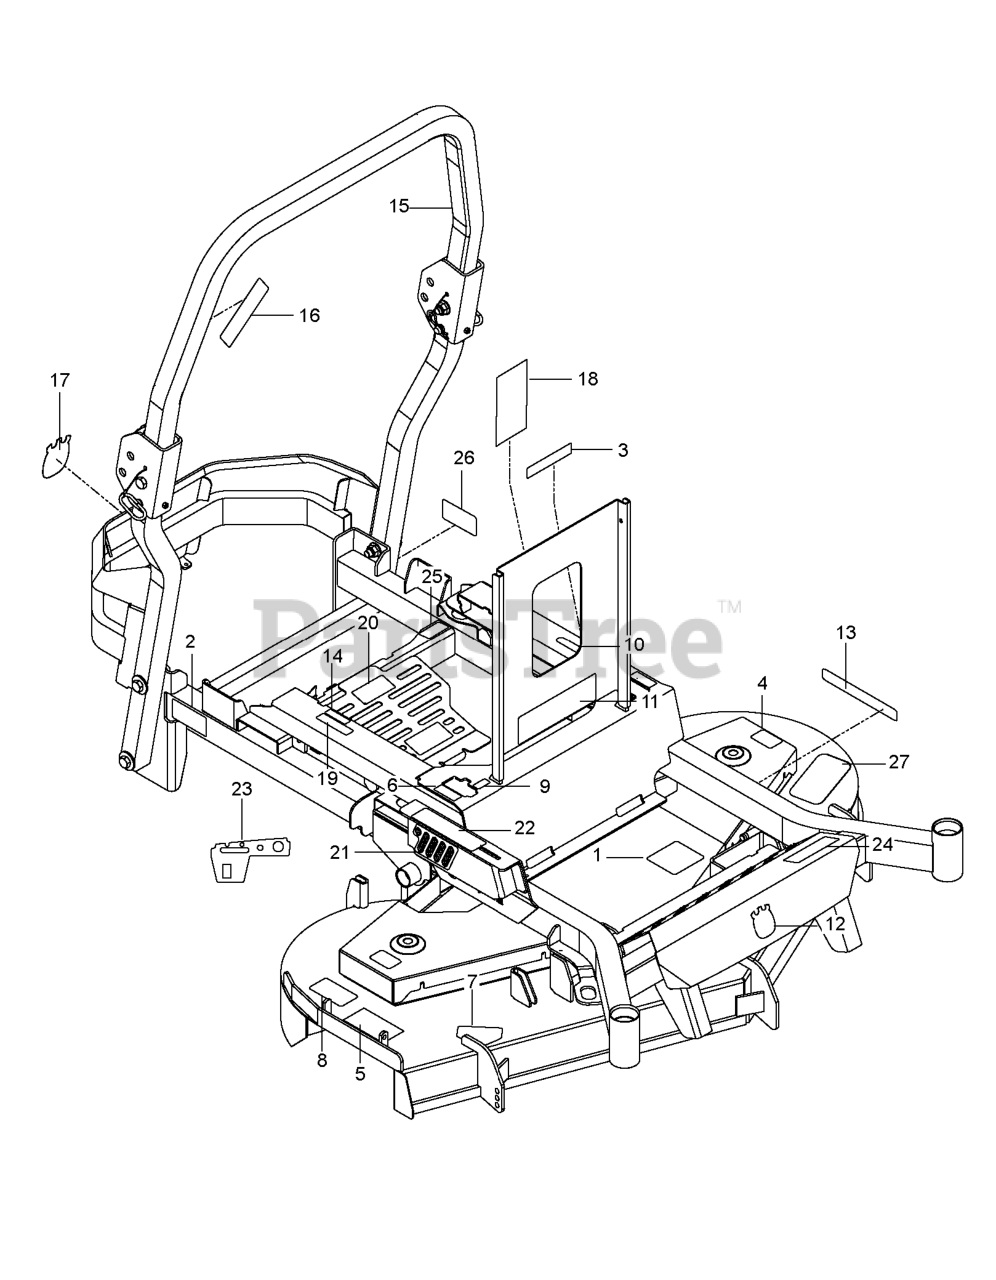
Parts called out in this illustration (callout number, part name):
1	DECAL, BELT ROUTING
2	DECAL, BELT DRIVE
3	EURO DECAL-BATTERY WARNIN6
4	DECAL.DECK.6MIL.EURO.NOSTEP
5	DECAL, EURO SEVERING
6	DECAL, MOTION CONTROL
7	DECAL, DECK DEFLECTOR, WARNING
8	DECAL.DECK.6MIL./DEF.SHLD.WARN
9	DECAL, F.S.T.
10	DECAL, PARK BRAKE
11	DECAL, WARNING
12	DECAL.AUGER.HUSQ.CROWN.SNOW
13	RP.DECAL.BADGE.170MM.TEXTLOGO
14	DECAL, FUSE
15	DECAL, ROPS
16	DECAL, ROPS, WARNING
17	DECAL, CROWN H, 110MM
18	DECAL, SERVICE
19	DECAL, WARNING SPARK ARRESTOR
20	HG_DECAL, ZT-3400
21	DECAL, HEIGHT
22	DECAL, RELEASE LEVER
23	DECAL, CONTROL, GAS
24	DECAL P-ZT 48
25	DECAL, FUEL
26	DECAL, PROP. 65
